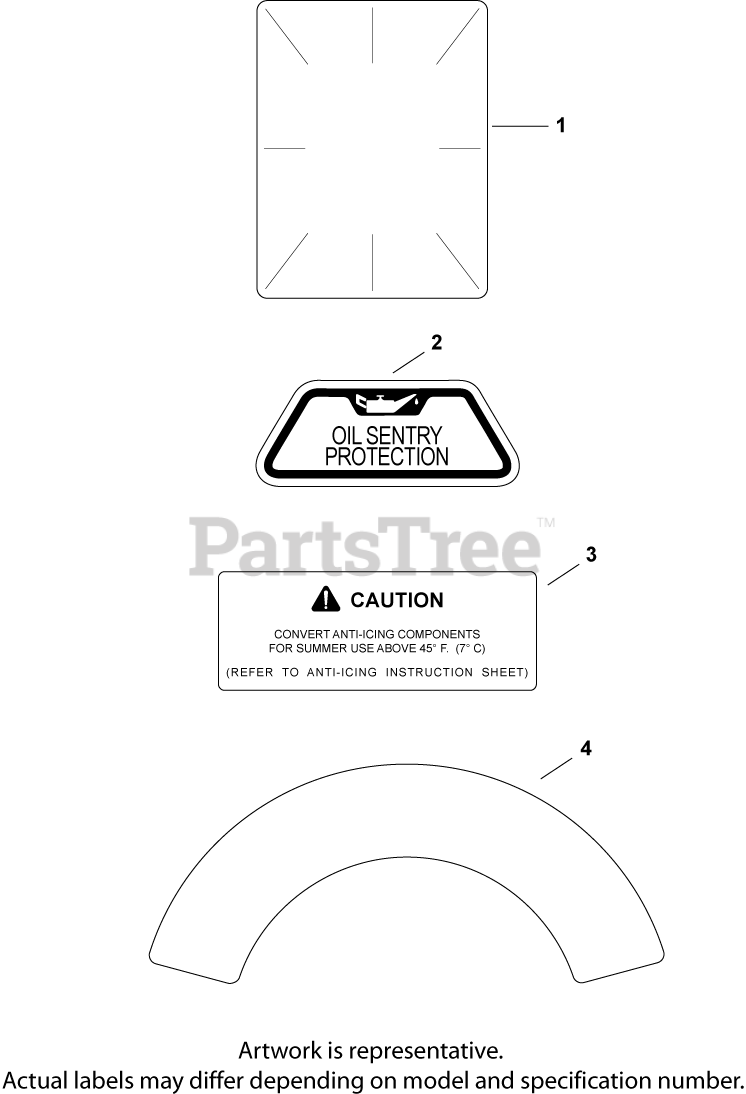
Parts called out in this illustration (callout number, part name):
1	DECAL, CLEAR LAMINATE USE 25 113 70-S
2	DECAL, OIL SENTRY - (#DSC)
3	DECAL, ANTI-ICING
4	DECAL, 18 HP
